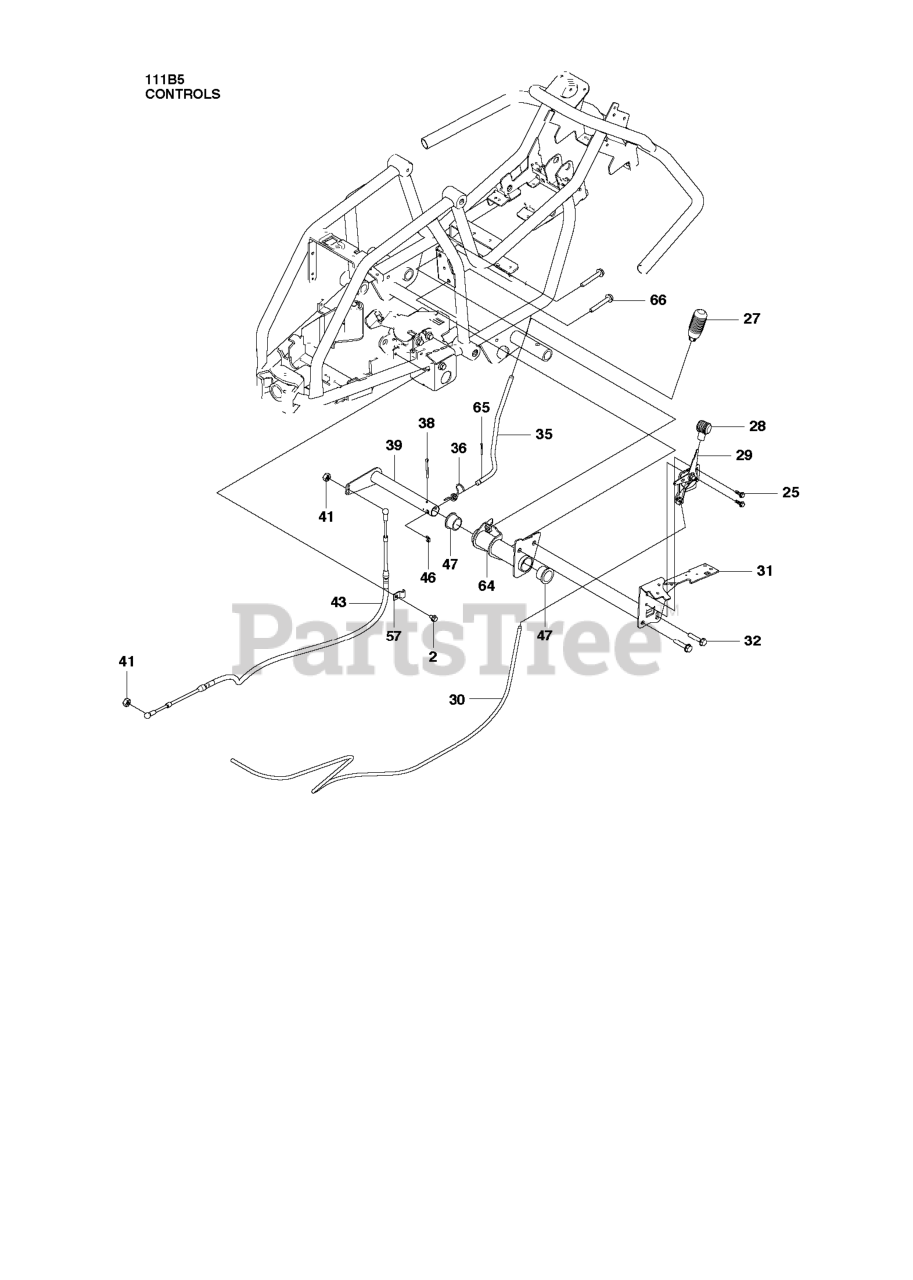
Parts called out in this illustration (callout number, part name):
27	GEAR STICK KNOB
29	THROTTLE CONTROL
41	LOCKNUT M5
46	Retaining Ring
47	BEARING FLANGE
65	Cotter Pin
66	SCREW
